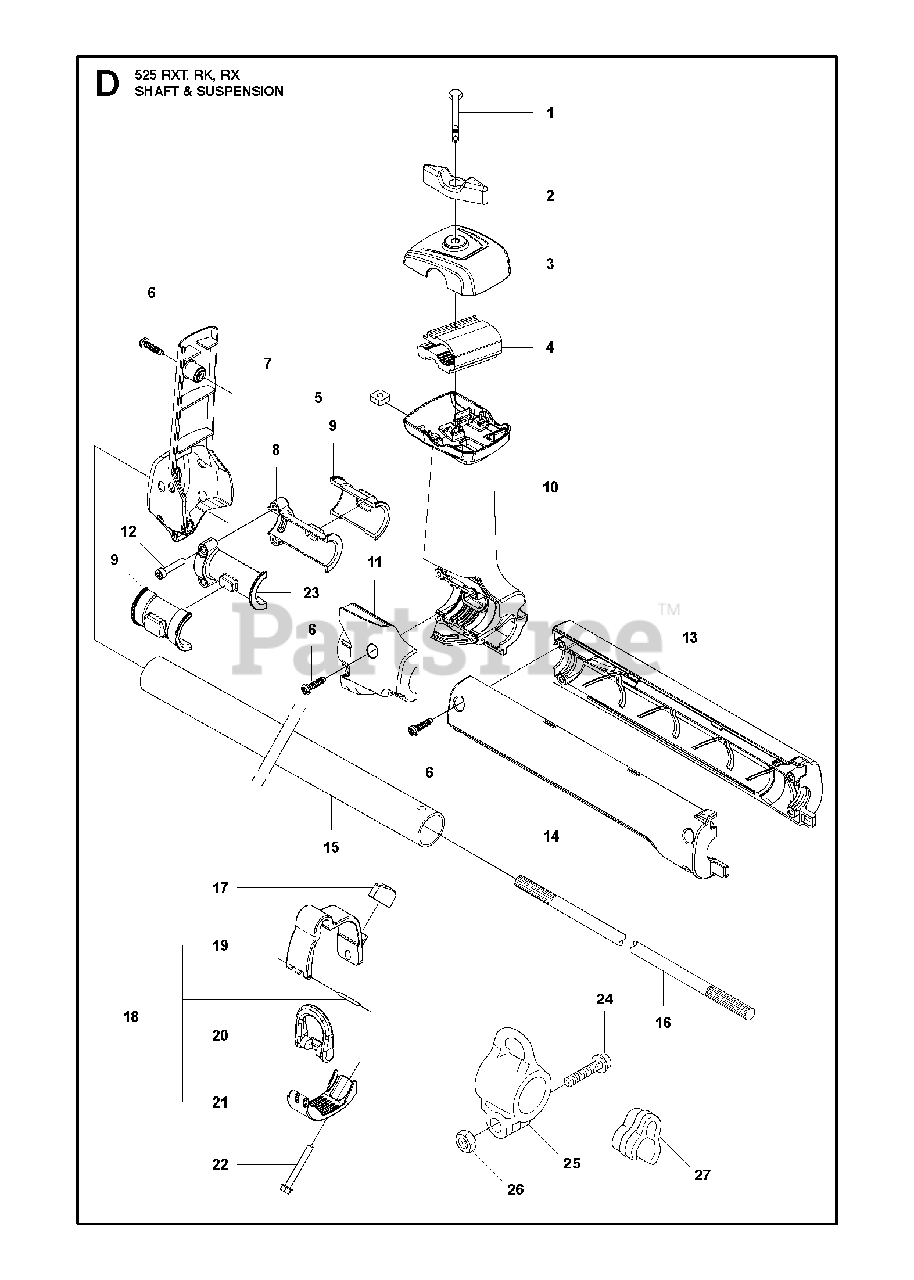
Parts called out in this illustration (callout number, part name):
1	%SCREW
5	NUT
6	SCREW ITXSCT MT5X20 T27 12.9
7	COVER TOWER
8	BRACKET (A)
9	ABSORBER
10	HANDLE BAR BRACKET COMP
11	COVER HANDLEBAR BRACKET
13	WEAR PROTECTION RIGHT
14	WEAR PROTECTION LEFT
15	TUBE COMP
16	DRIVESHAFT
17	KNOB
19	CLAMP UPPER
20	HOOK
21	CLAMP LOWER
22	SCREW M6S 5X40
23	BRACKET (B)
24	SCREW
25	HARNESS HOLDER
26	NUT
27	GROMMET
